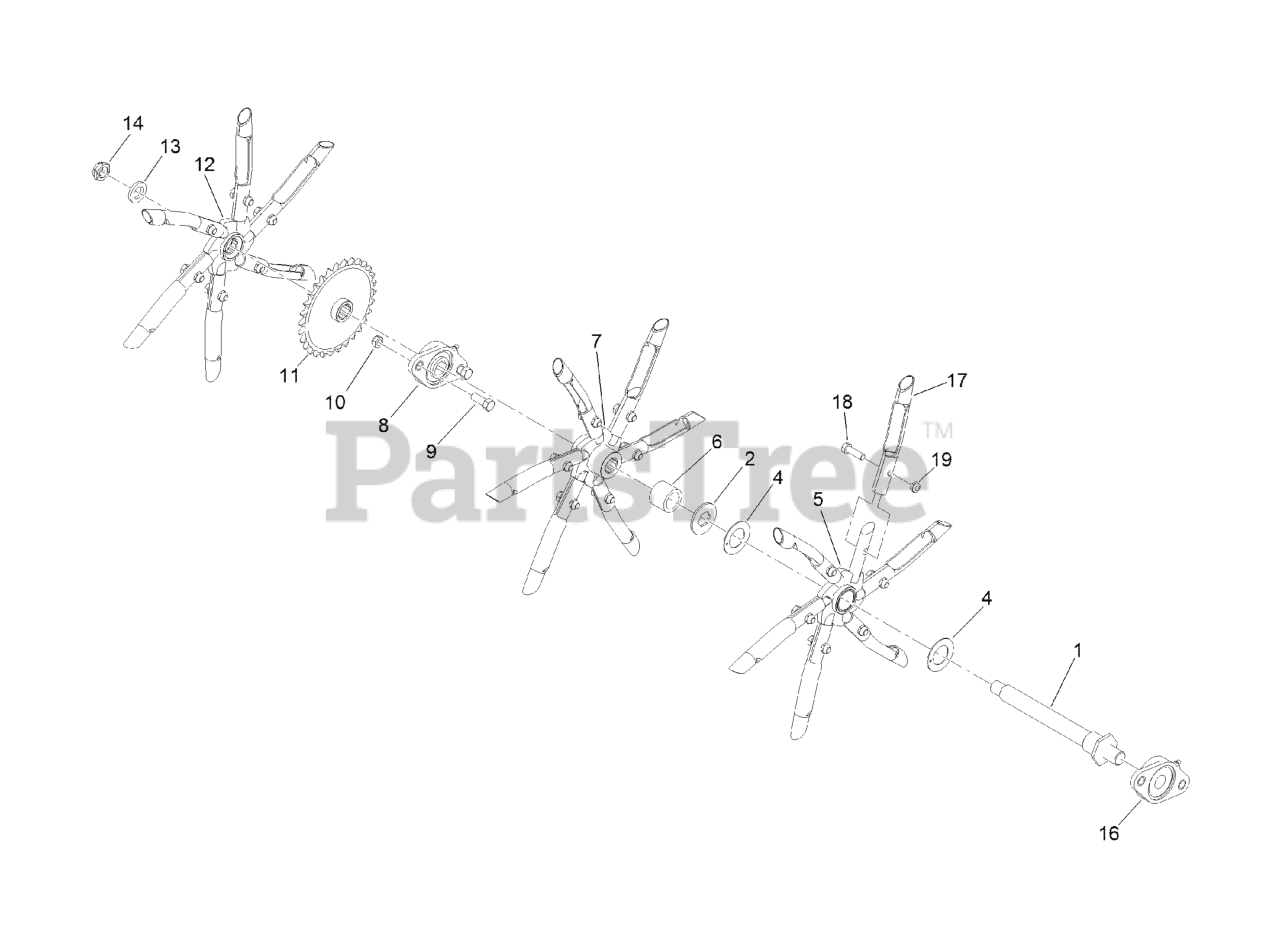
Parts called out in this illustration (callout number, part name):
1	TINE SHAFT ASM
2	KEEPER-TINE, FLOATING
4	WASHER-THRUST
5	FLOATING SPYDER ASM
6	SPACER-TINE
7	DRIVEN SPYDER ASM
8	BEARING-HEX BORE
9	SCREW-HH
10	NUT-LOCK
11	SPROCKET ASM
12	DRIVEN SPYDER ASM
13	WASHER-SPACER
14	NUT-LOCK
16	BEARING-ROUND BORE
17	TINE-CORING (3/4 INCH)
18	SCREW-HH
